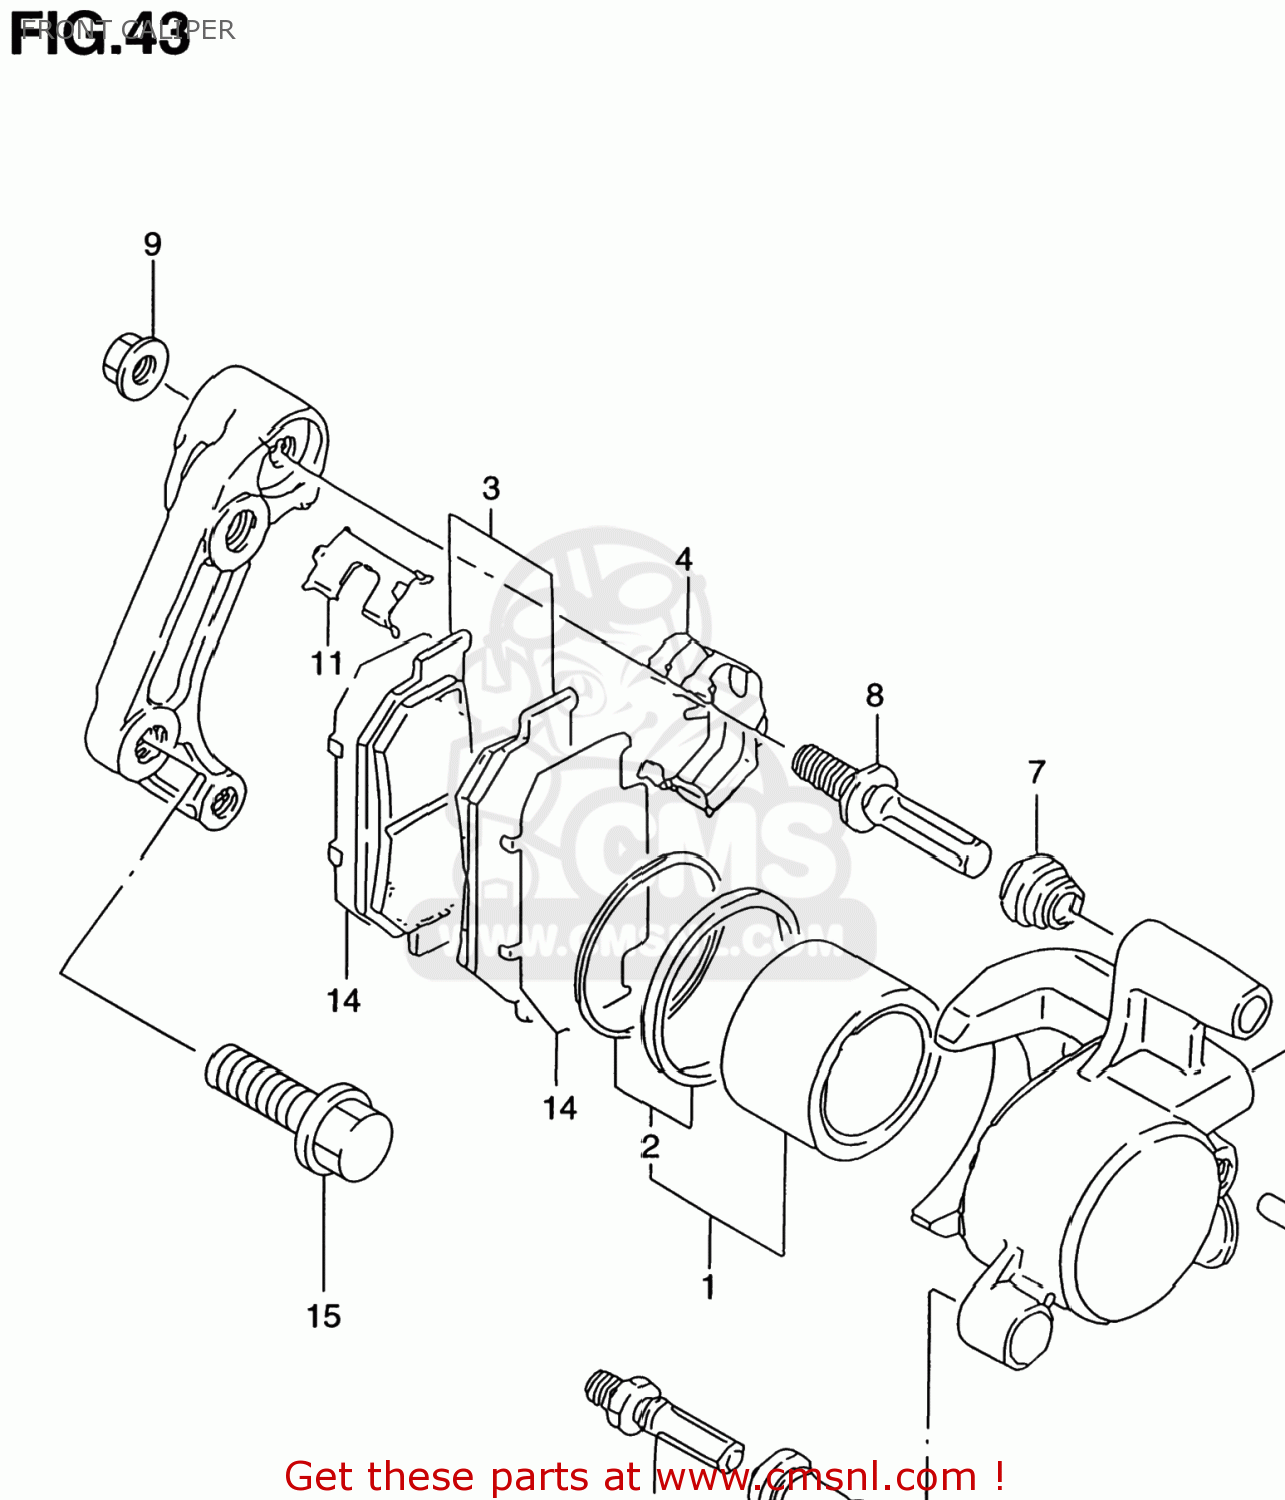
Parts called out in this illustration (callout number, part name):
1	PISTON SET
2	SEAL SET,PISTON
3	PAD SET (NAS)
4	SPRING
5	BOOT
6	BOLT
7	BOOT
8	PIN,SLIDE
9	NUT,SLIDE PIN
10	PIN,HANGER
11	RETAINER
12	BLEEDER
13	CAP,BLEEDER
14	SHIM
15	BOLT
